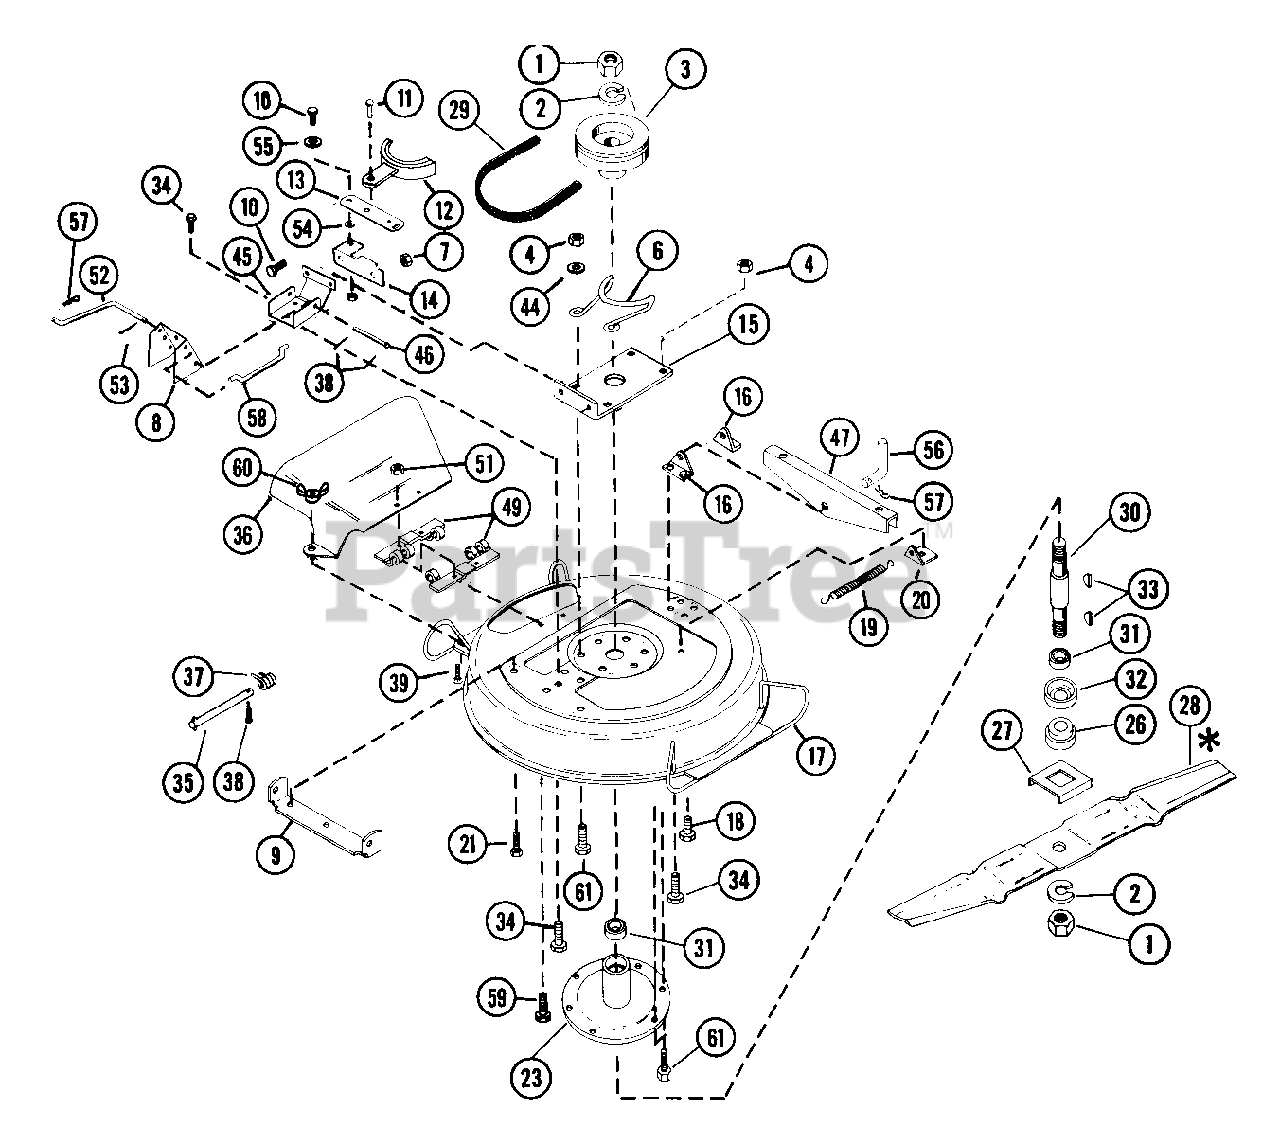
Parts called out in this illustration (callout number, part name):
1	NUT-JAM .75-10 PL
2	WSHR-LK .750X.188 MED PL
3	MOWER SHEAVE
4	NUT-LK-CTR .375-16 GR A PL
6	MOWER BELT FINGER
7	NUT-LK .312-18 GR A PL
8	MOWER ENGAGING ARM
9	FRONT MOUNTING BRACKET
10	BLT-HEX .31-18X.63 PL GR 2
11	RVT .25X.50 RH ST
12	BLADE BRAKE
13	MOWER BRAKE LEVER
14	BRAKE BRACKET
16	REAR MOUNTING BRACKET
17	28 MOWER PAN W/DECALS
18	BLT-SERHFWH .25-20X.50 PL
19	SG-TENS .072X.51X5.31 WLD 25
20	BRAKE CLIP
21	BLT-SCRHFWH .38-16X.50 PL
23	SPINDLE HOUSING
26	RETAINER HUB
27	BLADE TRAY
28	BLADE 28 IN
29	V-BELT
30	MOWER SPINDLE
31	BRG-BALL .750X1.781X.61
32	BEARING SLINGER
33	KEY-WDRF .188X.75X.313 SAE 9
34	BLT-SERHFWH .31-18X.50 PL
35	CLEVIS PIN
36	DISCHARGE CHUTE
37	SG-TORS .090X.37X.63
38	PIN-COTR .09X.75 PL
39	BLT-RDHDSQNK .25-20X.75 GR5PL
44	WSHR-FL-STL .406X.865X.094 PL
45	PIVOT BRACKET
46	PIN-CLEV .309X3.50 SP
47	SWIVEL BRACKET
49	HINGE PLATE
51	NUT-LK-CTR .250-20 PL
52	MOWER ENGAGEMENT LINK
53	PIN-COTR .12X.75 PL
54	SPACER
55	WSHR-FL-STL .328X1.0X.094
56	CLEVIS PIN
57	PIN-HAIR INT .08X.38X1.42 YWZC
58	MOWER BRAKE LINK
59	BLT-RDHDSQNK .25-20X.62 PL
60	NUT-WING .250-20
61	BLT-HEX .38-16X1.00 PL
